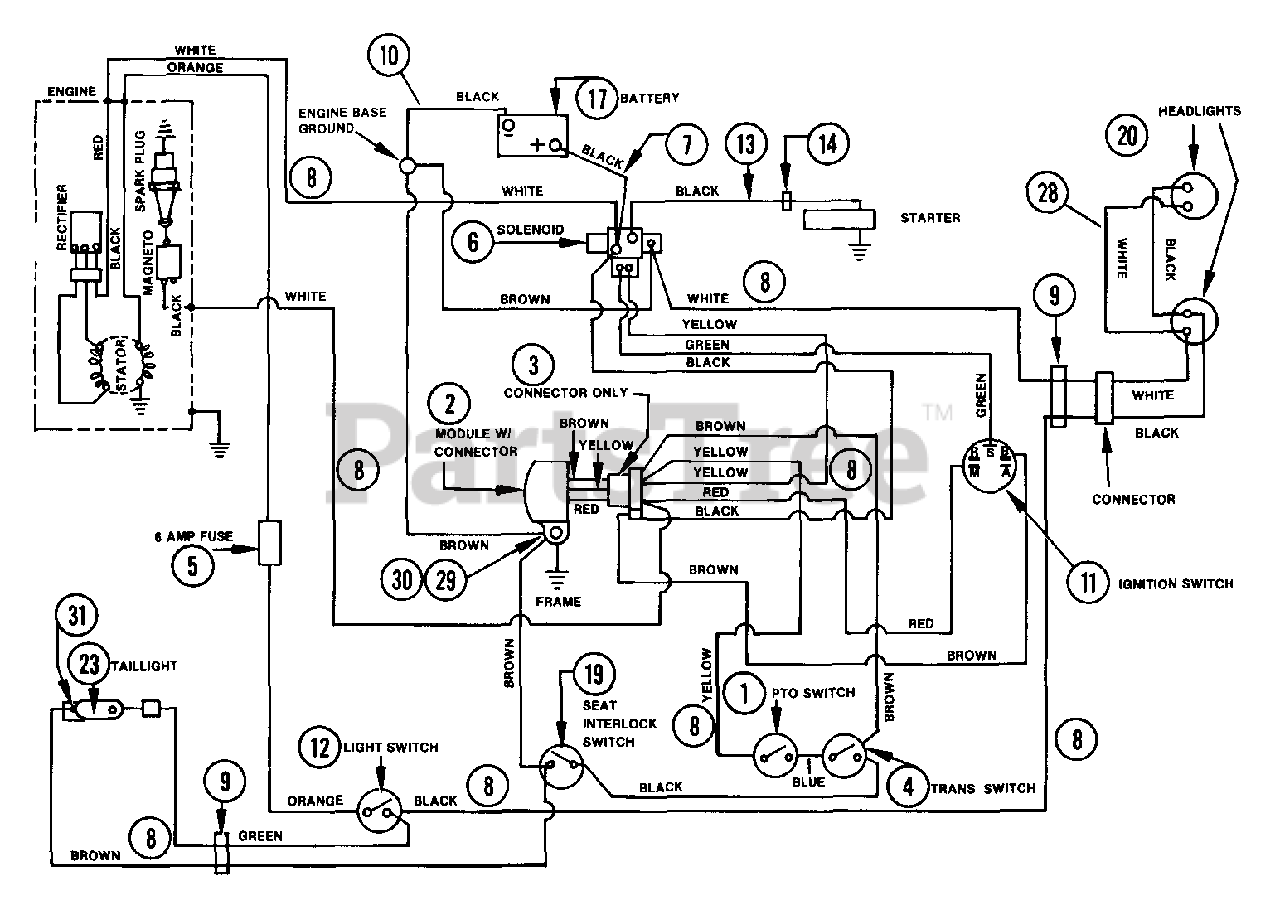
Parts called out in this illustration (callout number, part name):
1	SWITCH INTERLOCK
2	MODULE
3	CONNECTOR
4	SWITCH-NEUTRAL START N.O.
5	FUSE, 6 AMP
6	SOLENOID
7	GROUND CABLE
8	WIRE HARNESS 11HP
9	CLAMP LOOP
10	GROUND CABLE
11	IGNITION SWITCH AND KEY ASSEMB
12	LIGHT SWITCH
13	GROUND CABLE
14	TIE DOWN
17	BATTERY
19	SWITCH SEAT
20	HEAD LIGHT
23	TAIL LIGHT
23	TAIL LIGHT LENS
28	WIRE HARNESS - HEADLIGHT
29	SCR-MCH 10-24X.62 SLRH PL
30	NUT-KEPS 10-24 PL
31	MALE DISCONNECT ADAPTER
31	WSHR-LK .312X.097 PL HVY
31	NUT-JAM .312-24 PL
31	WSHR-LK 10X.047 MED PL
31	NUT 10-32 PL
